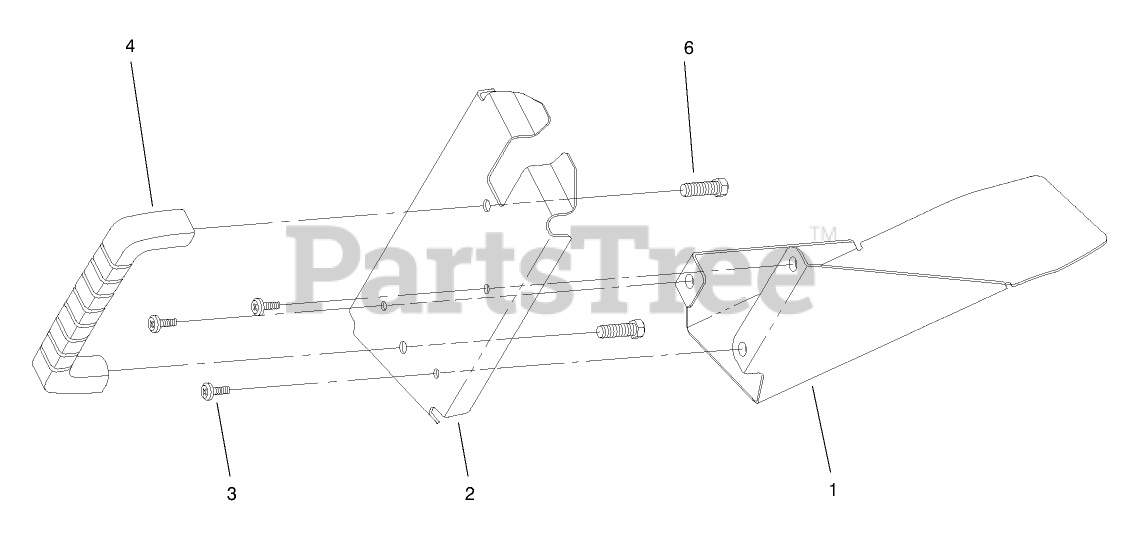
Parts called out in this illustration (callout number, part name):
1	SHIELD-DISCHARGE PLUG
2	COVER - DISCHARGE PLUG
4	HANDLE-DOOR
6	SCREW-HWH
